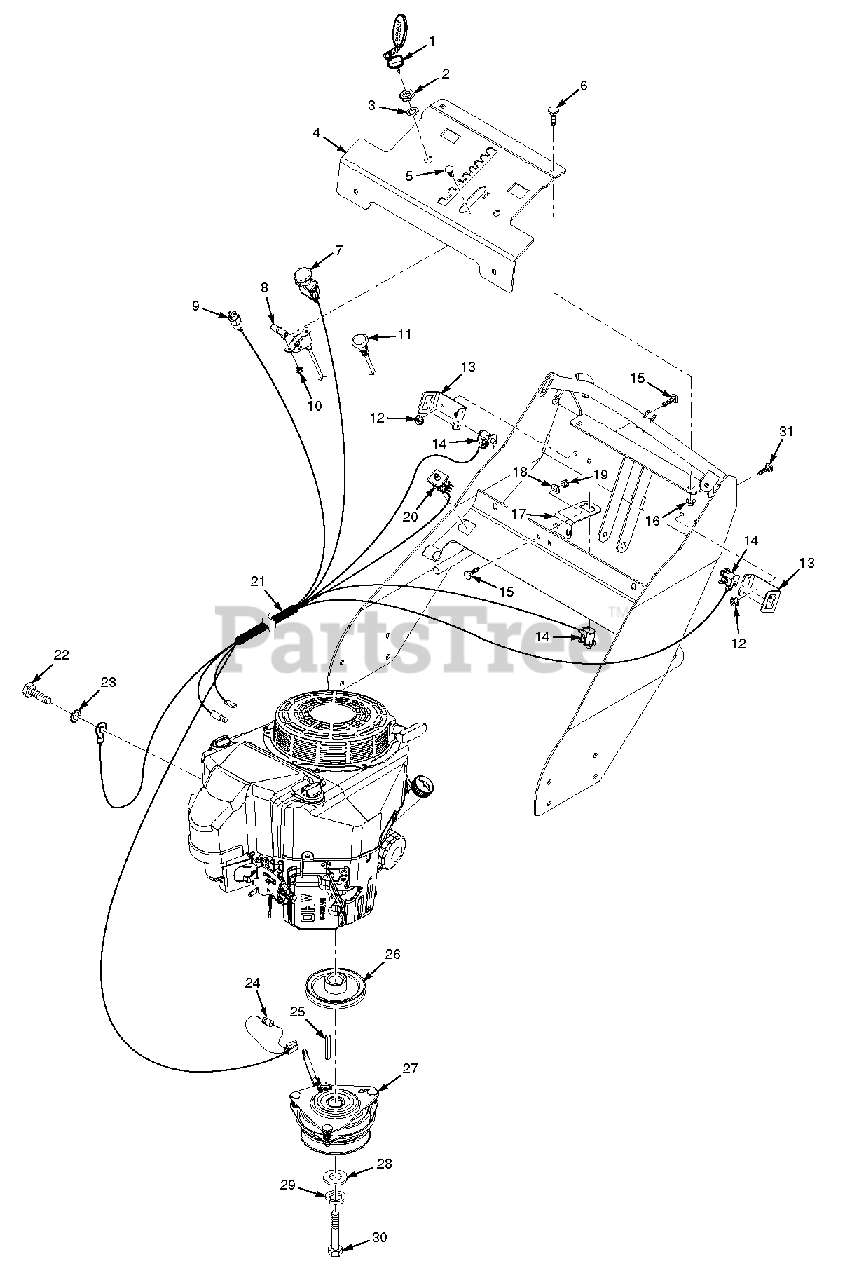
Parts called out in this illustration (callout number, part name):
1	Key Assembly w/Fob
1	Key w/Shroud
2	Nut, 5/8-32 Special
3	Lockwasher, 5/8" Internal Tooth
4	Instrument Panel w/Decal
5	Bolt, Carriage #10-24 x 1/2"
6	Bolt, Carriage 5/16-18 x 3/4"
7	PTO Switch
8	Throttle Cable
9	Key Switch
10	Nut, Elastic Stop #10-24
11	Choke Control
12	Nut, Serrated Flange 1/4-20
13	Bracket, Operator Presence Switch
14	Switch
15	Bolt, Carriage 1/4-20 x 3/4"
16	Nut, Serrated Flange 5/16-18
17	Bracket, Neutral Switch
18	Flatwasher, 5/16-.375 x .875 x .083
19	Nut, Elastic Stop 1/4-20
20	Switch, Brake Interlock
21	Wire Harness
22	Bolt, Hex Head M8-1.25 x 14
23	Lockwasher, 5/16" External Tooth
24	Diode
25	Key, 1/4 x 1/4 x 2-1/2"
26	Pulley, 4-1/2" Dia. 1" Bore
27	Electric Clutch Assembly
28	Flatwasher, 7/16-.469 x 1.75 x .25
29	Lockwasher, 7/16" spring
30	Bolt, Hex Head 7/16-20 x 3" w/t Patch
31	Bolt, Carriage 1/4-20 x 1-1/4"
